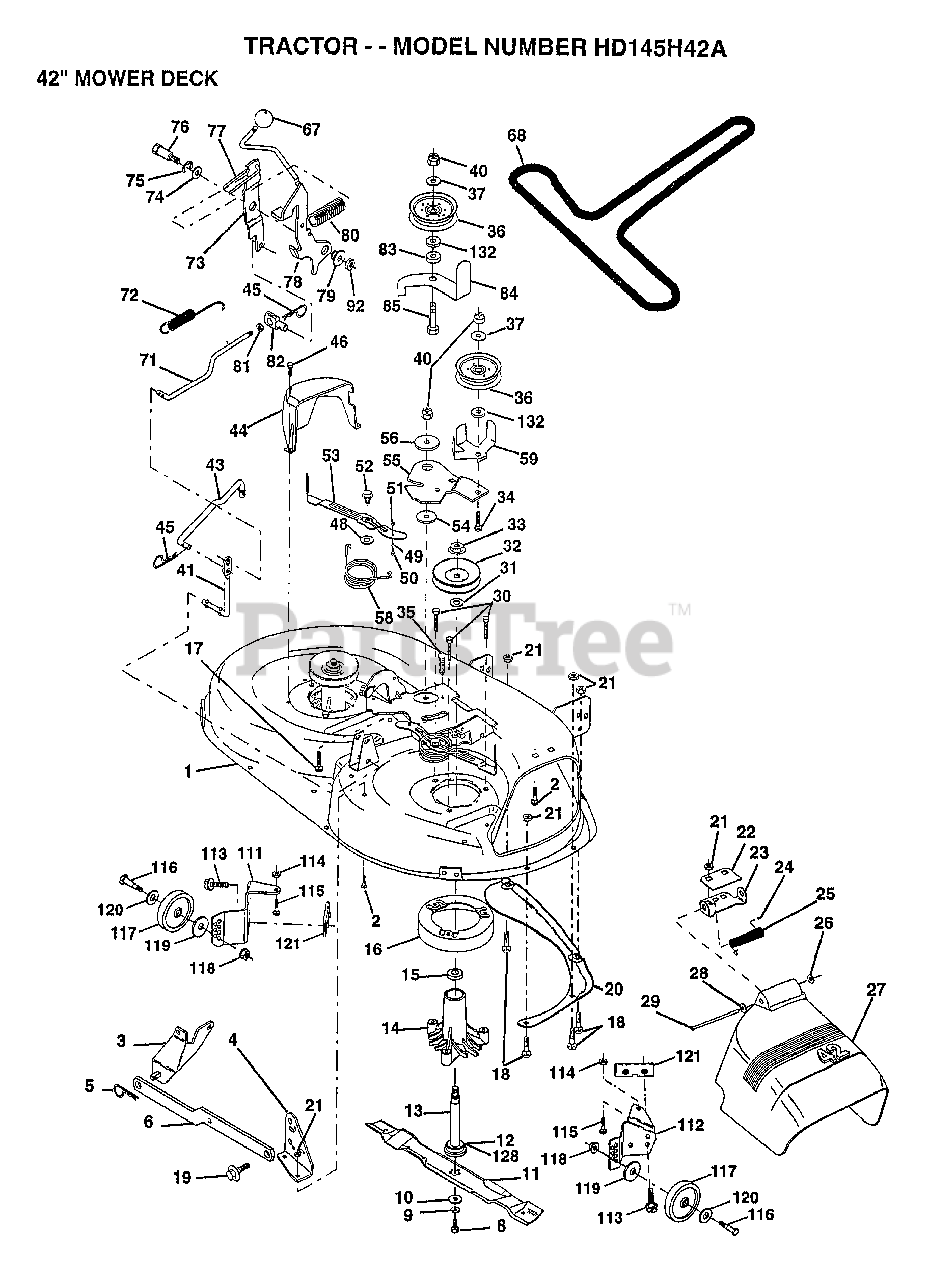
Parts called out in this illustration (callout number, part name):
1	DECK.WELD.42.
2	BOLT
3	BRKT ASM SWAY BAR
4	BRKT DECK SW BAR
8	BLADE BOLT
10	WASHER.HARD.BLADE
11	"BLADE.42"" HIPERF"
12	BEARING.BALL
14	HSG ASM MANDREL
15	BEARING
16	STRIPPER RND MWR
17	BOLT RDHD 3/8-16
18	BOLT
19	BOLT SHD 5/16-18
22	STIFFENER BRKT
23	DEFLECTOR BRKT
24	CAP-SLEEVE LT
25	SPRING TORSION
26	NUT PUSH M
27	DEFLECTOR.SHIELD
28	WASHER
29	HINGE ROD
31	WASHER
32	PULLEY.MANDREL.42
34	BOLT
35	XMAS TREE FASTNER
36	FLAT IDLER PULLEY
37	WASHER
41	PIVOT ROD
43	ROD CLUTCH W/NIBS
44	GUARD MAND LH BLK
45	RETAINER M
46	SCREW.1/4-20X5/8
48	HARD SMALL WASHER
49	ROLLER ASM-CAM
50	SHOULDER BOLT
51	LOCKNUT
52	BOLT.SHLD.5/16-18
54	HARDENED WASHER
55	ARM-IDLER
56	SPACER RETAINER
58	SPRING TORSN BRAK
59	GUARD IDLER TUV
67	KNOB T(3/8 HOLE)
68	BELT.V.T-PATH
71	ROD CLUTCH 38/42
72	RETURN SPRING
73	CLUTCH ARM SECOND
74	WASHER
75	RING
76	SHOULDER BOLT
77	SPRING KEEPER
78	LEVER ASM-CLUTCH
79	BUSHING
80	SPRING.CLUTCH.MWR
81	NUT
82	TRUNION ADJ
83	WASHER
84	"KEEPER-BELT,FIXED"
85	BOLT RDHD 3/8-16
92	NUT
111	BRACKET.GWHL.LH.
112	BRACKET.GWHL.RH.
113	SCREW
116	BOLT M
117	WHEEL.GAGE.BLK.PL
118	LOCKNUT
119	WASHER
120	WASHER
121	BRACKET.EXTRD.GWL
128	WASHER.FELT.
132	WASHER GT
